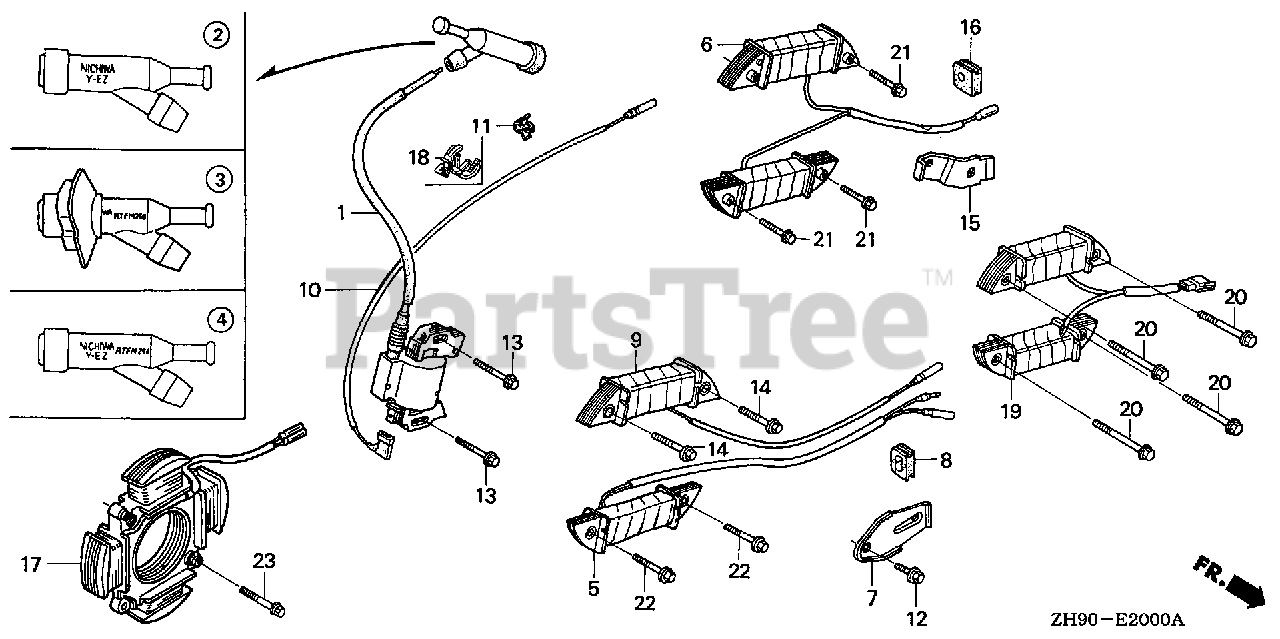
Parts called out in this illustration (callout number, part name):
1	COIL ASSY., IGNITION
4	CAP ASSY., NOISE SUPPRESSOR (Honda Code 3526837). (NICHIWA Y-EZ RTFM256)
7	CLAMP, WIRE
8	GROMMET, WIRE
9	COIL ASSY., CHARGE (3A)
10	WIRE, STOP SWITCH (370MM)
12	BOLT, FLANGE (6X12) (CT200)
13	BOLT, FLANGE (6X28) (CT200) Use up to Engine SN 1530314.
14	BOLT, FLANGE (6X32)
